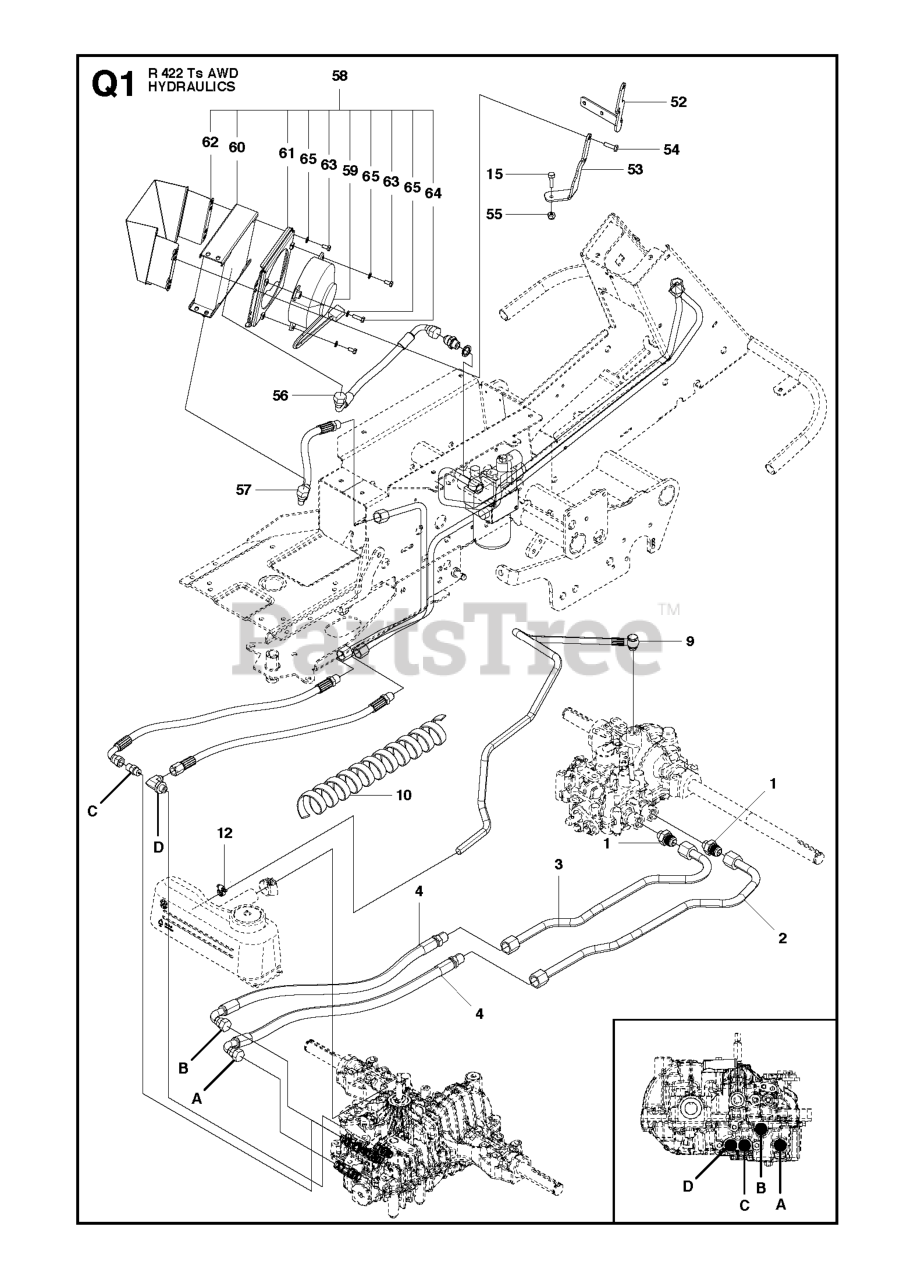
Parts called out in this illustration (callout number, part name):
1	PIPE FITTING
10	HOSE GUARD
15	BOLT FLANGE - M6X20
54	SCREW EHHFM
55	LOCKNUT M6
65	WASHER - M6
